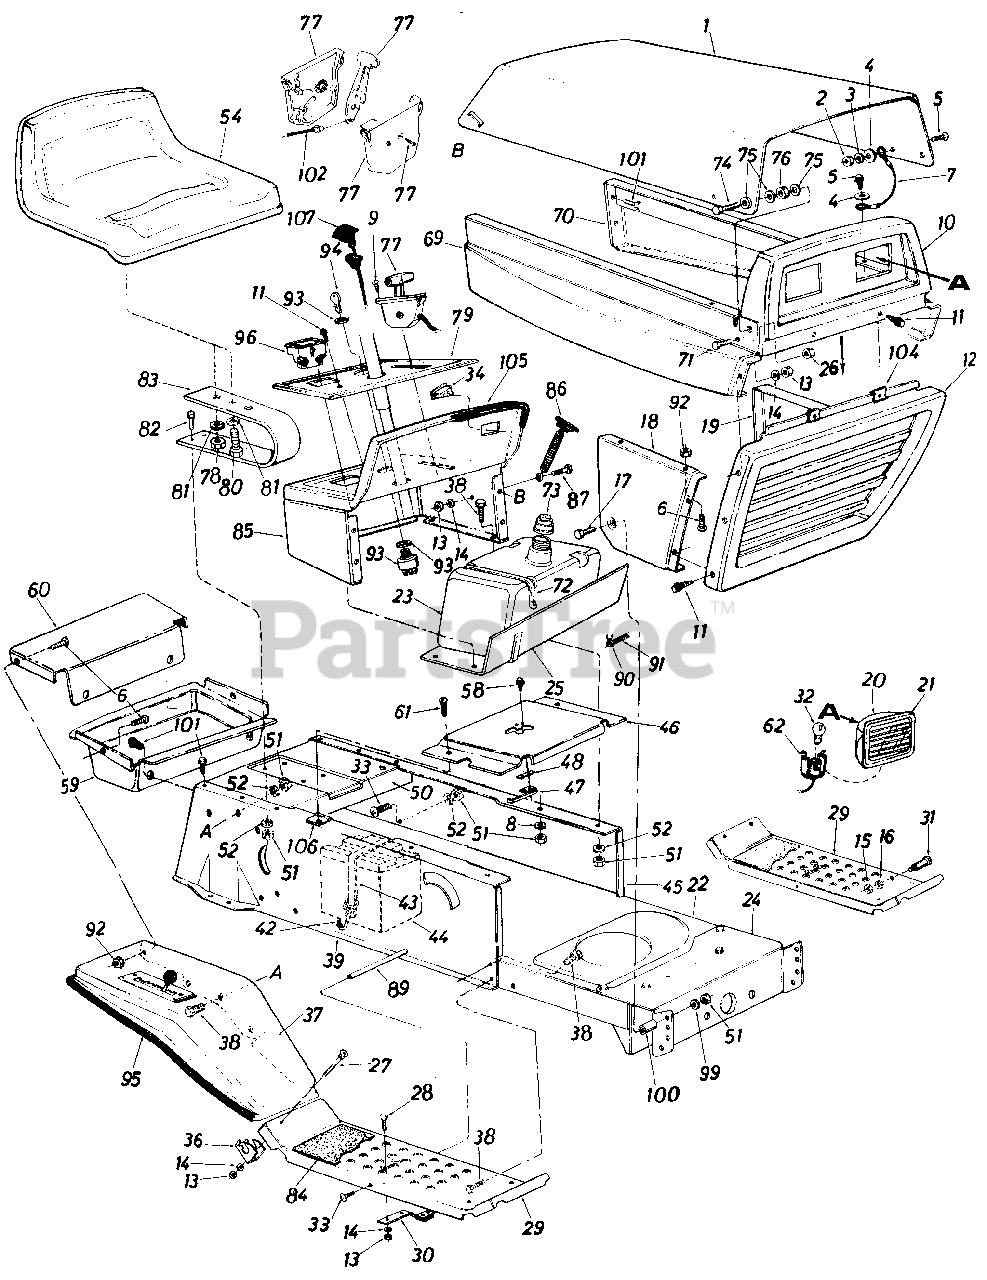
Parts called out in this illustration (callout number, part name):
3	L-Wash. #10 I.D.
4	Fl-Wash. .25" I.D. x .62"
5	Truss Scr. #10-24 x .375"*
6	Truss Hd. Scr. #10-24 x .50"*
7	Hood Stop
8	Ext. L-Wash. 5116"
9	Truss Mach. AB-Tap Scr. #10 x .44
10	Front Grille Upper Ass'y
11	Hex AB-Tap Scr. #10 x .50"
14	L-Wash. 1/4" I.D.
15	Hex Nut 3/8-16 Thd.
16	L-Wash. 3/8" I.D.*
17	Hex Bolt 5/16-18 x 1.50"*
18	R.H. Lower Side Panel
19	L.H. Lower Side Pane
20	Headlight Housing
21	Headlight Lens
22	Lower Frame
23	Fuel Tank
24	Front Pivot Brkt.
25	Fuel Tank Support
26	Hex Cent. L-Nut 3/8-16 Thd.
27	Carriage Bolt 1/4-20 x 2.00"*
28	Carriage Bolt 1/4-20 x .62"*
29	Running Board
30	Blade Brake Ass'y.
31	Shld. Bolt .50 Dia. x .84
32	Head Lamp
33	Truss Mach. Scr. 5/16-18 x .75" Lg.*
34	Light Switch
36	Fender Clamp
37	Fender
39	R.H. Side Frame
42	Battery Strap Hook
43	Battery Hold Down Strap
44	12-V Battery
45	L.H. Side Frame
46	Shift Cover
47	Reverse Safety Switch
48	Insulator Nut Plate
50	Hitch Plate
51	Hex Nut 5/16-18 Thd.
52	L-Wash. 5/16" I.D.*
54	Seat Ass'y.
58	Hex AB-Tap Scr. #8 x .50"
59	Tool Tray
62	Twist Lock-Lamp Socket
69	Side Panel-R.H.
70	Side Panel-L.H.
71	Hex Bolt 1/4-20 x .62" Lg.
72	Tie Strap
73	Fuel Cap Gauge
74	Hex Bolt 3/8-16 x 1.00" Lg.*
75	Fl-Wash. .380" I.D. x l.00n
76	Rubber Wash. .38" I.D. x .87" O.D.
77	Throttle Control Box Ass'y.
78	Hex Nut 1/2-1 3 Thd.
79	Dash Panel Insert
80	Hex Bolt 1/2-13 x 1.0" Lg.
81	L-Wash. 1/2" I.D.
82	Hex Bolt 5/16-18 x 1.00"*
83	Seat Spring
84	Foot Pad
87	Hex Bolt 1/4-20 x .50" Lg.
89	Running Board Rod
90	Hose Clamp
91	Fuel Line
92	Hex Sems Nut #10-24 Thd.
93	Ignition Switch
94	Ignition Key
95	Trim Strip-57" Lg.
96	Ammeter
99	Belleville Wash. .34" I.D.
100	Spacer
101	Hex Wash. Hd. AB-Tap Scr. 1/4-20 x .62
102	Throttle Control Wire
104	Speed Nut #10Z
105	Trim Strip-15"
106	Speed Nut #10Z
107	Choke Control 29" Lg.
